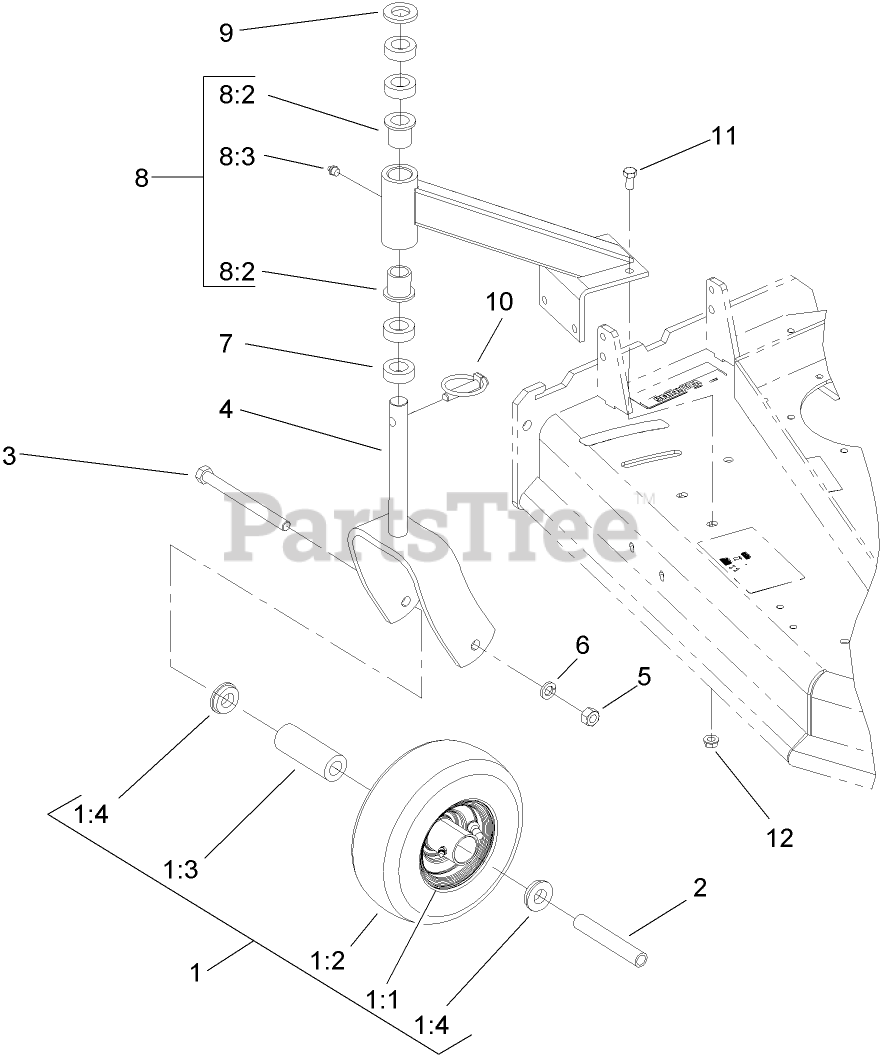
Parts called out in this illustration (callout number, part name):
1	WHEEL AND TIRE ASM
1:1	Rim
1:3	BEARING
1:4	BUSHING
2	SPACER
3	SCREW-HH
4	FORK
5	NUT-HH
6	WASHER-LOCK
7	SPACER-CASTER
8	SUPPORT ASM
8:2	BEARING-FLANGED
8:3	FITTING-GREASE
9	WASHER-FLAT
11	SCREW-HH
12	NUT-HHF, WHIZ
